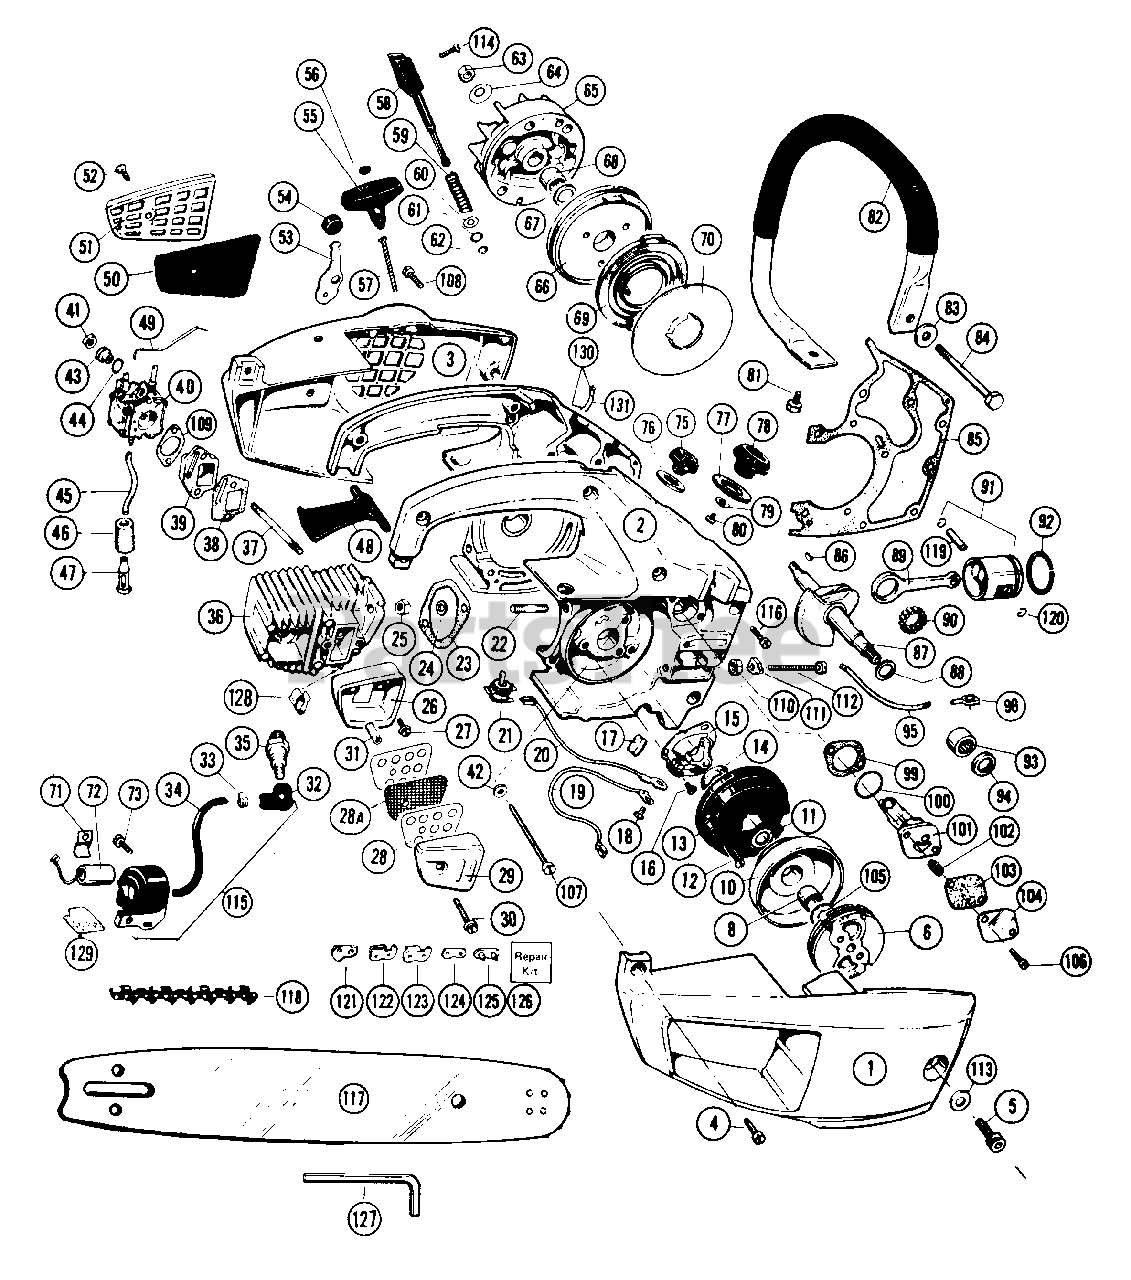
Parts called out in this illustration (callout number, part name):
1	Barclamp
2	Crankcase Ass'y. Inc.22,75-76,85,93-94, 110-112,130-131
3	Fan Housing
4	Screw-Bar Clamp-rear
5	Barclamp Screw
6	Clutch Ass'y.
8	Bushing-Clutch Drum
10	Drum & Sprocket Ass'y. Inc. Ref. 8
11	Spacer-Clutch (inside)
12	Screw-Point Cover
13	Cover-Breaker Points
14	Seal-Breaker Points Cover
15	Breaker Points Ass'y.
16	Screws-Breaker Points Base
17	Felt-Cam Wiper
18	Screw-Terminal
19	Lead Wire-Points To Coil
20	Lead Wire-Points To Switch
21	Stop Switch Ass'y.
22	Stud-Cylinder Mounting
23	Gasket-Cylinder
24	Lockwasher-Cylinder
25	Nut-Cylinder
26	Body-Muffler
27	Screw-Muffler Body
28	Baffle-Muffler
28A	Screen-Spark Arresting
29	Cover-Muffler
30	Screw-Muffler Cover
31	Spacer-Muffler
32	Boot-Spark Plug
33	Connector-Spark Plug
34	Lead-High Tension
35	Spark Plug
36	Cylinder Ass'y. Inc. Ref. 37
37	Stud-Carburetor Mount
38	Gasket-Carburetor Adapter
39	Adapter-Carburetor
40	REPL BY 530 03 50-11
41	Nut-10-24
42	Washer-Fiber
43	Spacer-Choke
44	Wave Washer
45	Line-Fuel (Bulk No. 8133)
46	Filter Felt-Fuel Pick-up
47	Weight-Fuel Pick-up
48	Trigger-Throttle
49	Wire-Throttle
50	Air Filter (Gray)
51	Cover-Air Filter
52	Screw-Cover Air Filter
53	Shutter-Choke
54	Bumper-Choke Lever
55	Handle-Starter Rope
56	Plug-Starter Handle
57	Rope-Starter
58	Plunger-Oil Pump
59	Spring-Pump Plunger
60	Washer-Pump Plunger
61	O-Ring-Pump Plunger (Top)
62	O-Ring-Pump Plunger (Bottom)
63	Nut-Flywheel
64	Washer-Ramp Conical
65	Flywheel Ass'y.
66	Starter Pulley Ass'y. Inc. Ref. 68
67	Thrust Washer
68	Bearing-Starter Pulley
69	Spring-Starter Recoil
70	Plate-Starter Pulley Back-up
71	Clamp-Condenser
72	Condenser
73	Screw-Sems (Coil)
75	Oil Cap Ass'y. Inc. Ref. 76
76	Gasket-Oil Cap
77	Gasket-Gas Cap
78	Gas Cap Ass'y. Inc. Ref. 77-79-80
82	Handlebar
83	Washer-1/4 (Handlebar, Top)
85	Gasket-Crankcase
86	Woodruff Key
87	Crank Shaft
88	Washer-Crankshaft Thrust
89	Connecting Rod
90	Bearings-Crank Pin Roller
91	Piston Ass'y. Inc. Ref. 119-120
92	Piston Ring
93	Bearing-Crankshaft
94	Seal-Crankshaft
95	Line-Impulse (Bulk No. 8133)
98	Check Valve
99	Gasket-Oil Pump Body
100	O-Ring-Oil Pump Body
101	Oil Pump Body Ass'y.
102	Filter-Oil Pump
103	Gasket-Oil Pump Cover
104	Cover-Oil Pump
105	Thrust Washer (Outside)
109	Gasket-Carburetor
110	Nut-Adjusting Screw
111	Pin-Bar Adjusting
112	Screw-Bar Adjusting
113	Washer-Barclamp Screw
114	Screw-Oil Plunger Lock
115	Coil & Lamination Ass'y. Inc. 32 - 34
116	Screws-Crankcase
118	Chain-12" Bar
118	Chain-14" Bar
119	Wrist Pin
120	Retaining Ring-Wrist Pin
121	Drive Link-Chain
122	Cutter LH-Chain
123	Cutter RH-Chain
124	Tie Strap-Chain
125	Pre-set Tie Strap-Chain
126	Repair kit-Chain
127	Bar Wrench
128	Clip-High Tension lead (1st fin-bottom)
129	Coil Insulator
130	Vent Plug Ass'y.
131	Line-Oil Tank Vent (7" Long Cut from No. 8133 Tubing)
